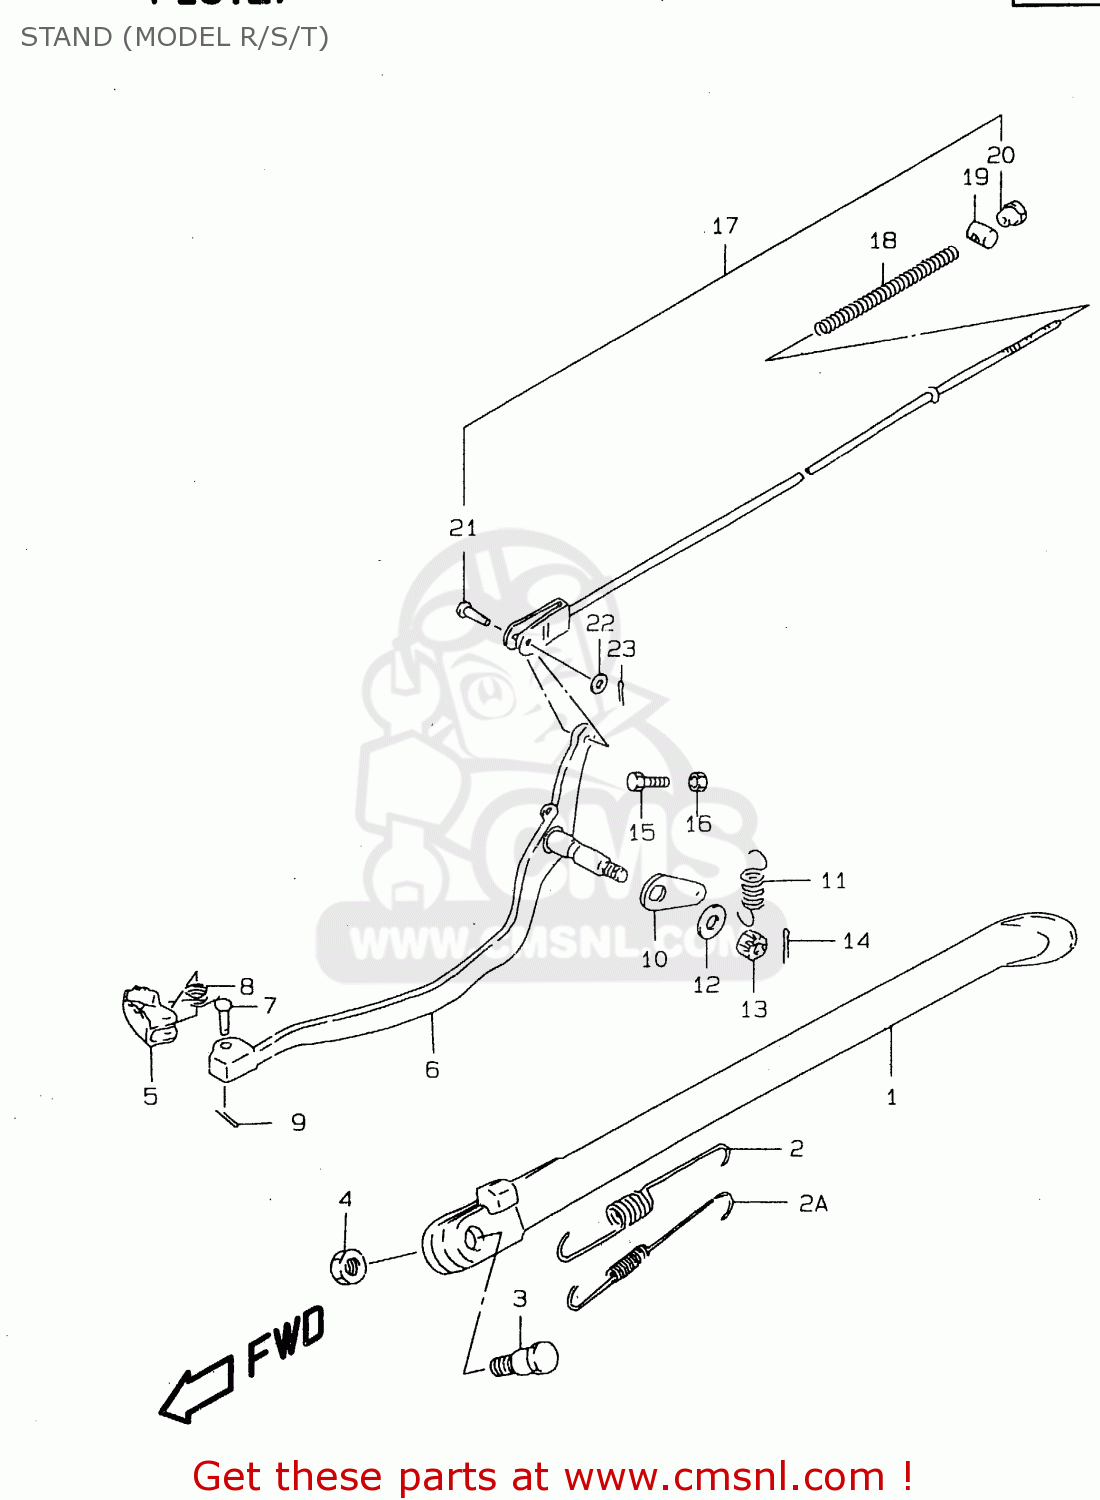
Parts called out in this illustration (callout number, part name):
1	STAND,PROP
2	SPRING
2A	SPRING
3	BOLT L:30
4	NUT
5	PEDAL,BRAKE
6	ARM,BRAKE PEDAL
7	PIN
8	SPRING
9	PIN
10	ARM,BRAKE RETURN SPRING
11	SPRING
12	WASHER
13	NUT
14	PIN 20X20
15	BOLT(6X23)
16	NUT 6MM
17	ROD ASSY,RR BRAKE
18	SPRING
19	PIN
20	NUT (6MM)
21	PIN(L:13.5)
22	WASHER
23	PIN 20X20
